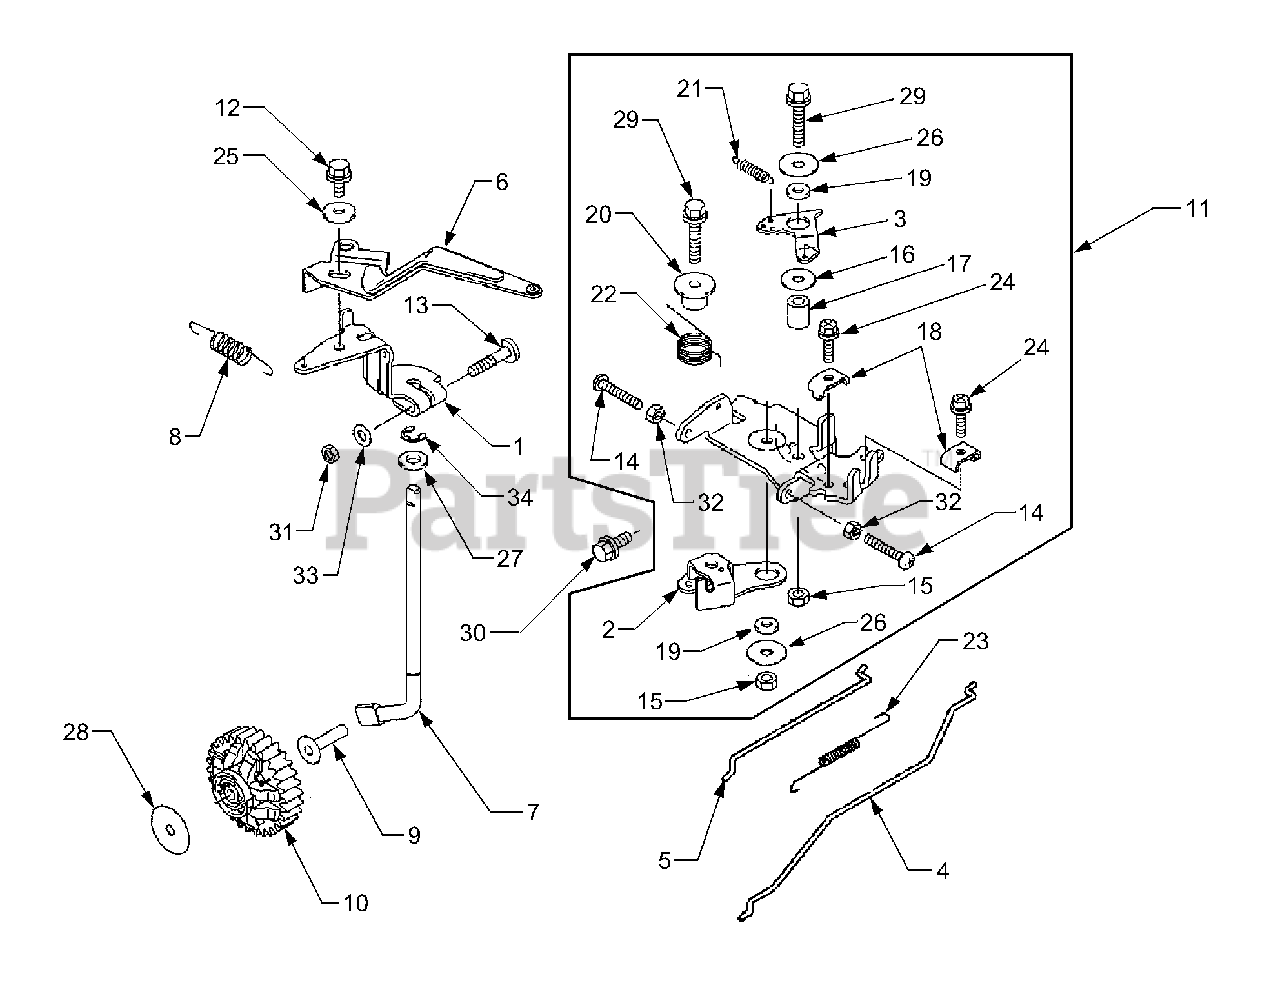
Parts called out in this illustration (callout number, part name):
2	Lever, Throttle
6	Arm Assembly
7	Arm, Governor Pivot
8	Spring, Governor
10	Gear Assembly, Governor
11	Panel, Control Complete
12	Bolt
14	Screw, 5 x 30
16	Washer, 6 x 19 x 1.2
19	Collar, 6 x 13 x 2.3
26	Washer, 6.5 x 22 x 1.2
27	Washer, 8.3 x 16 x 2.3
28	Washer, 6.2 x 30 x 0.5
29	Bolt, Flanged
30	Bolt, Flanged
31	Nut, Hex
33	Washer, Plain
34	Circlip, E-Ring
